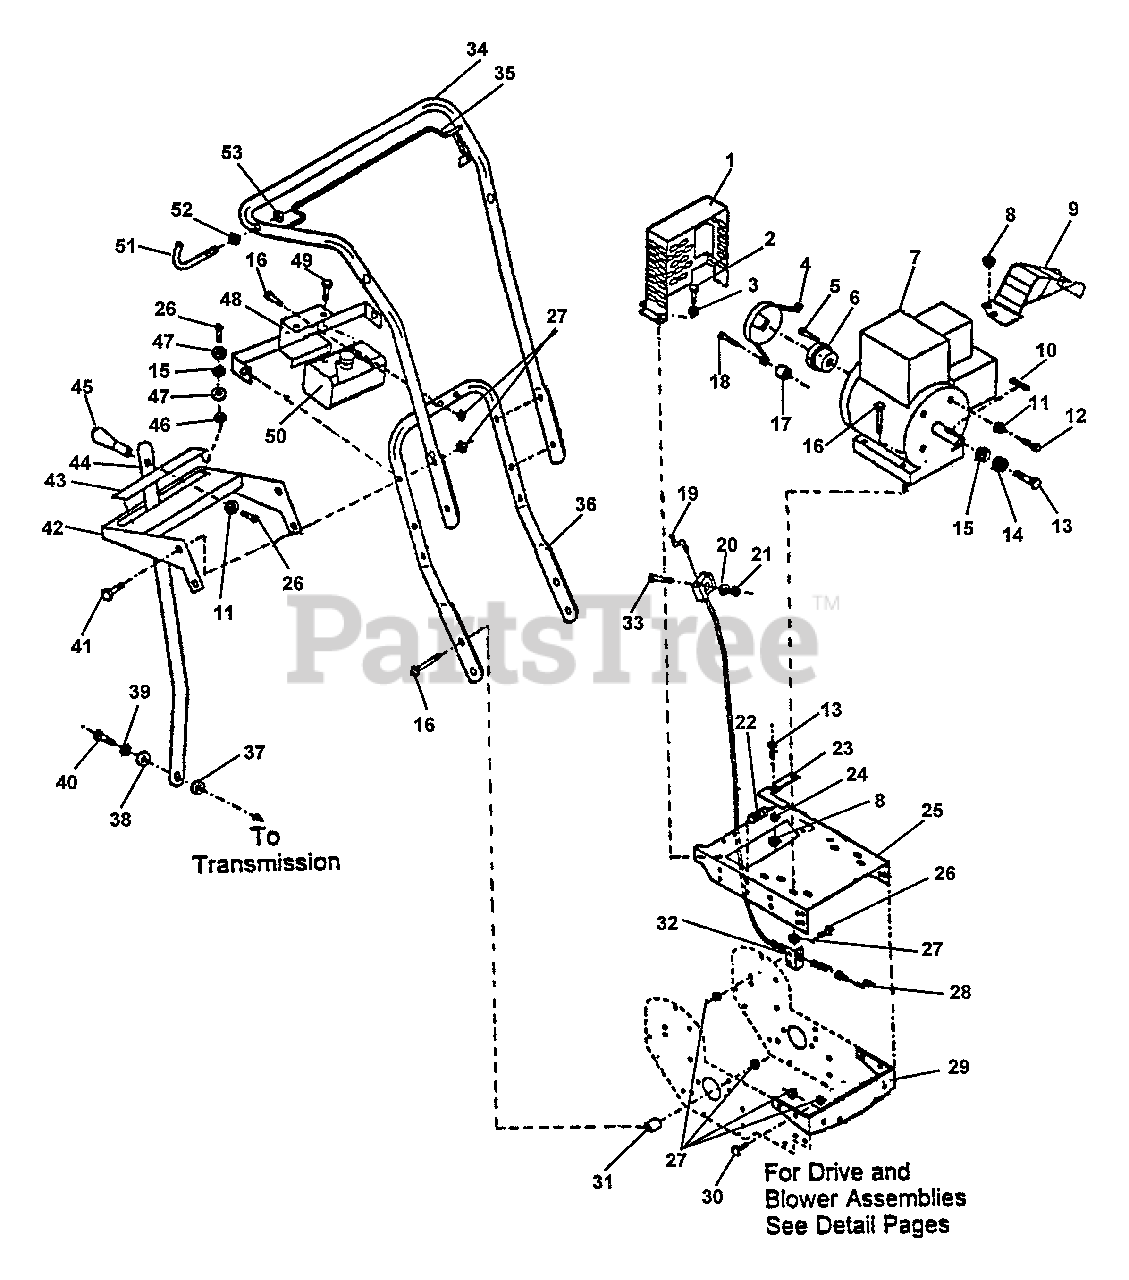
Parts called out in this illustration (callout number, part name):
3	LOCKWASHER - 10
4	HOUSING, STARTER - 5 HP
4	HOUSING, STARTER - 8 HP
5	SCREW, 8-32 X 1/2"
7	BRIGGS & STRATTON ENGINE 5HP
7	BRIGGS & STRATTON ENGINE 8HP
11	LOCKWASHER - 5/16"
12	BOLT - 5/16-24 X 1"
20	WASHER - 8
33	BOLT - 8/32 X 1-3/4"
38	WASHER - 1/4"
39	LOCKWASHER - 1/4"
40	BOLT - 1/4-28 X 3/4"
41	BOLT - 5/16-18 X 1-3/4"
